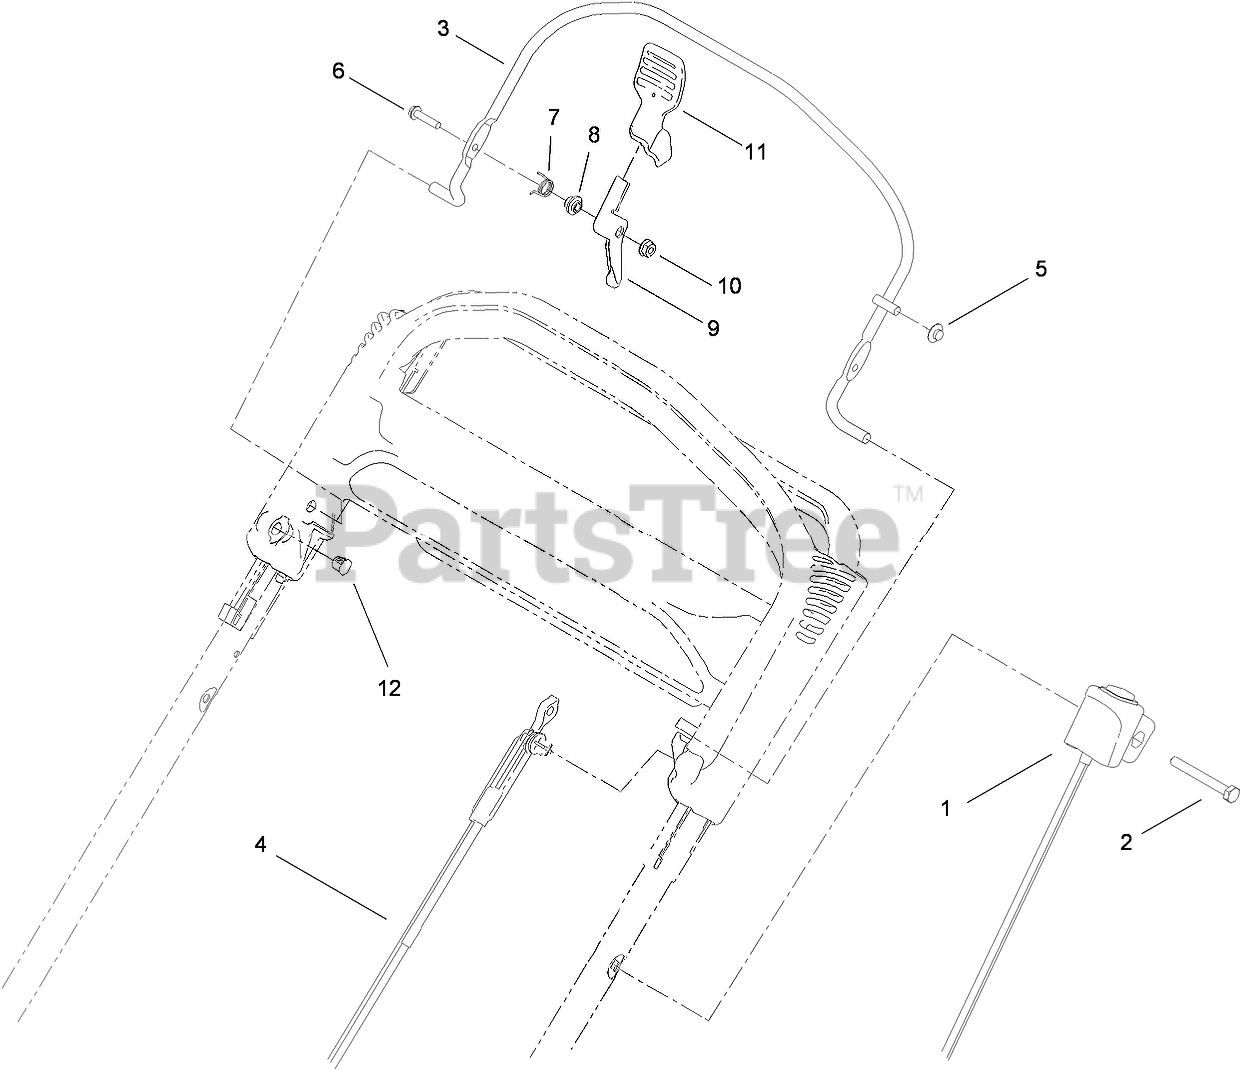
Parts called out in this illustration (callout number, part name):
1	SWITCH HOUSING ASM
2	SCREW-HH
3	BAIL-BRAKE
4	CABLE-BRAKE
5	NUT-SPEED
6	SCREW-HWH
7	SPRING-TORSION
8	SPACER
9	LEVER
10	NUT-LOCK, FLANGE
12	Plug-Dome
